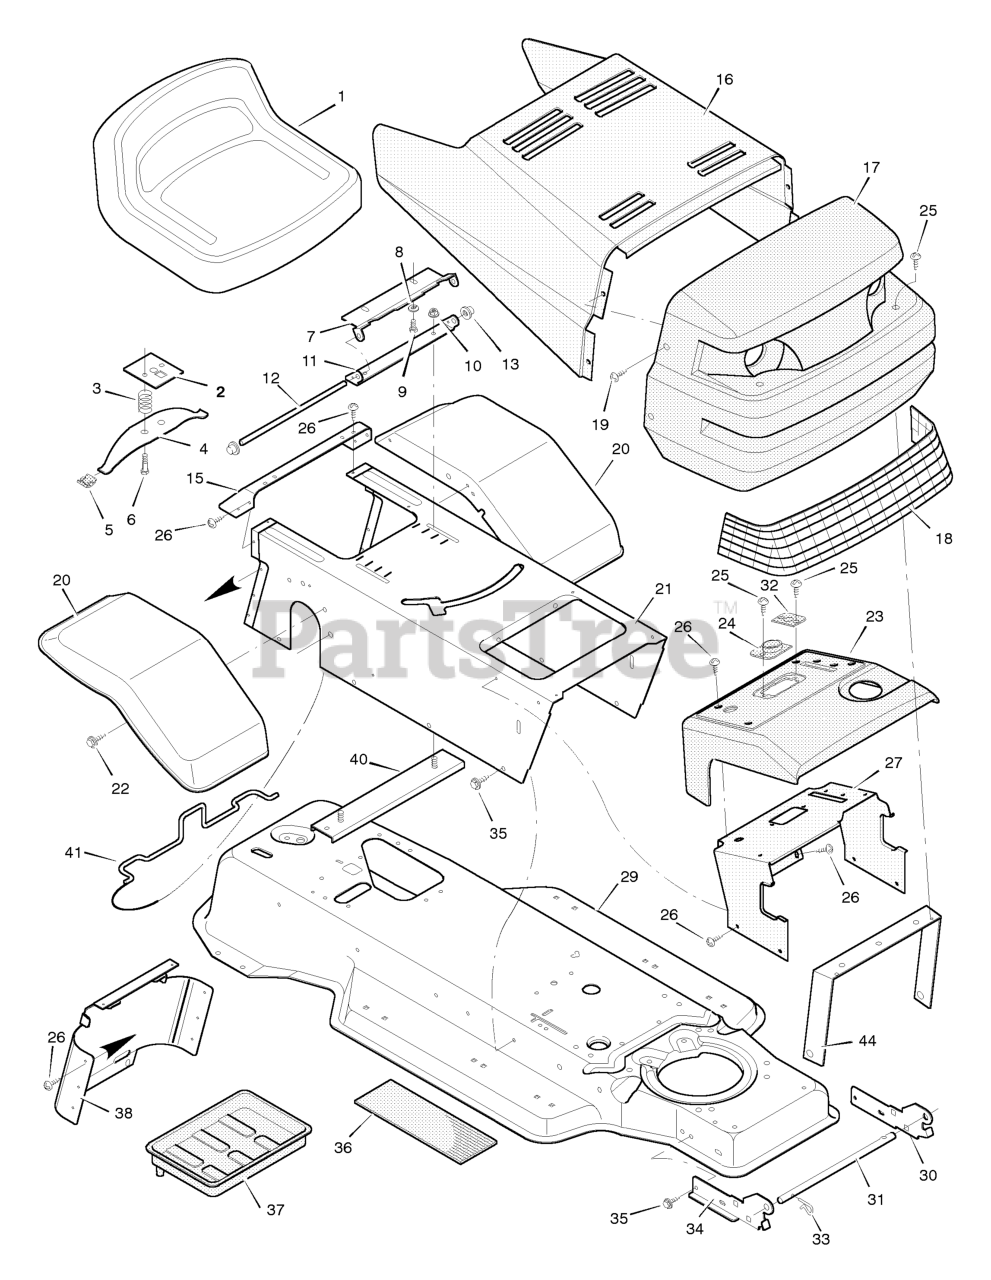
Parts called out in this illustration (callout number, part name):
2	Plate Assembly, Switch
3	Spring, Compression
4	Spring, Seat
5	Glide, Spring
6	Bolt, Shoulder
7	Support, Seat
8	Lockwasher
9	Bolt, Hex
10	Locknut, Flange
11	Bracket, Pivot
12	Rod, Pivot
13	Cap, Push On
15	Fender, Apron
17	Grille Assembly
21	Console Assembly
23	Dash Panel
24	Bearing, Steering
26	Screw
27	Support, Dash
29	Frame Assembly
30	Bracket, Left Grille
31	Rod, Pivot
32	Bearing
33	Pin, Hair
34	Bracket, Right Grille
37	Tray, Battery
38	Cap, Console
39	Bolt
40	Channel Assembly
41	Clamp, Battery
44	Brace, Grille
